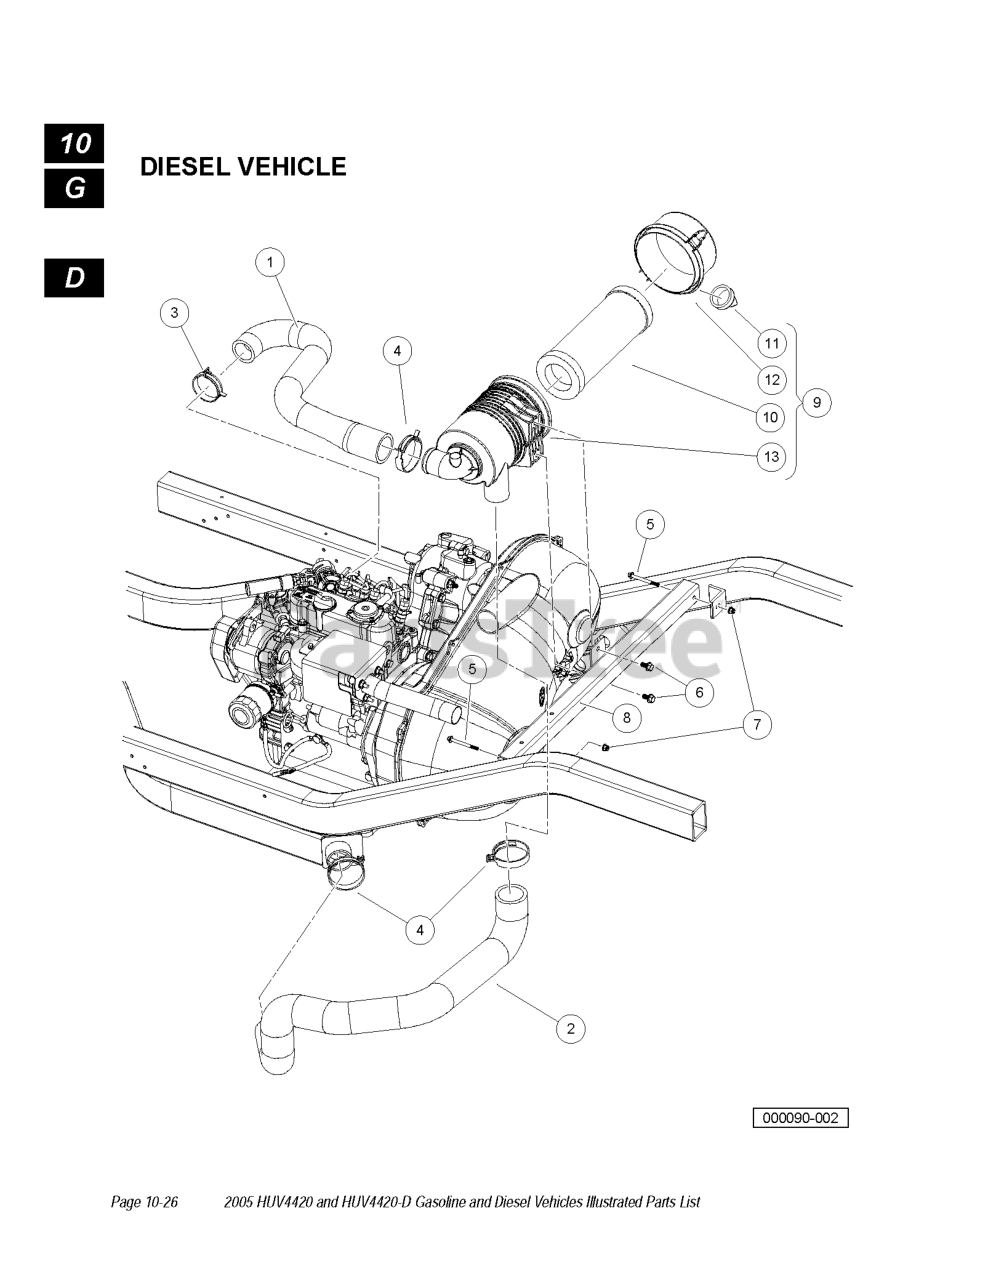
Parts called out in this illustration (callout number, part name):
1	HOSE, INTAKE, D722
2	HOSE, INTAKE, PRIMARY
3	CLAMP, HOSE, CTB 55MM
4	CLAMP, HOSE, CTB 64MM
5	BOLT-M6X1.0X65 HEX FL HD, BLK
6	BOLT FLG, M8X1.25X16 LOCTITE
7	NUT FLG, M6 X 1.0 NYLON
9	FILTER, AIR, CANISTER, 5IN
10	ELEMENT, FILTER, AIR, 5 IN
11	AIR FILTER VALVE
12	AIR FILTER CAP
